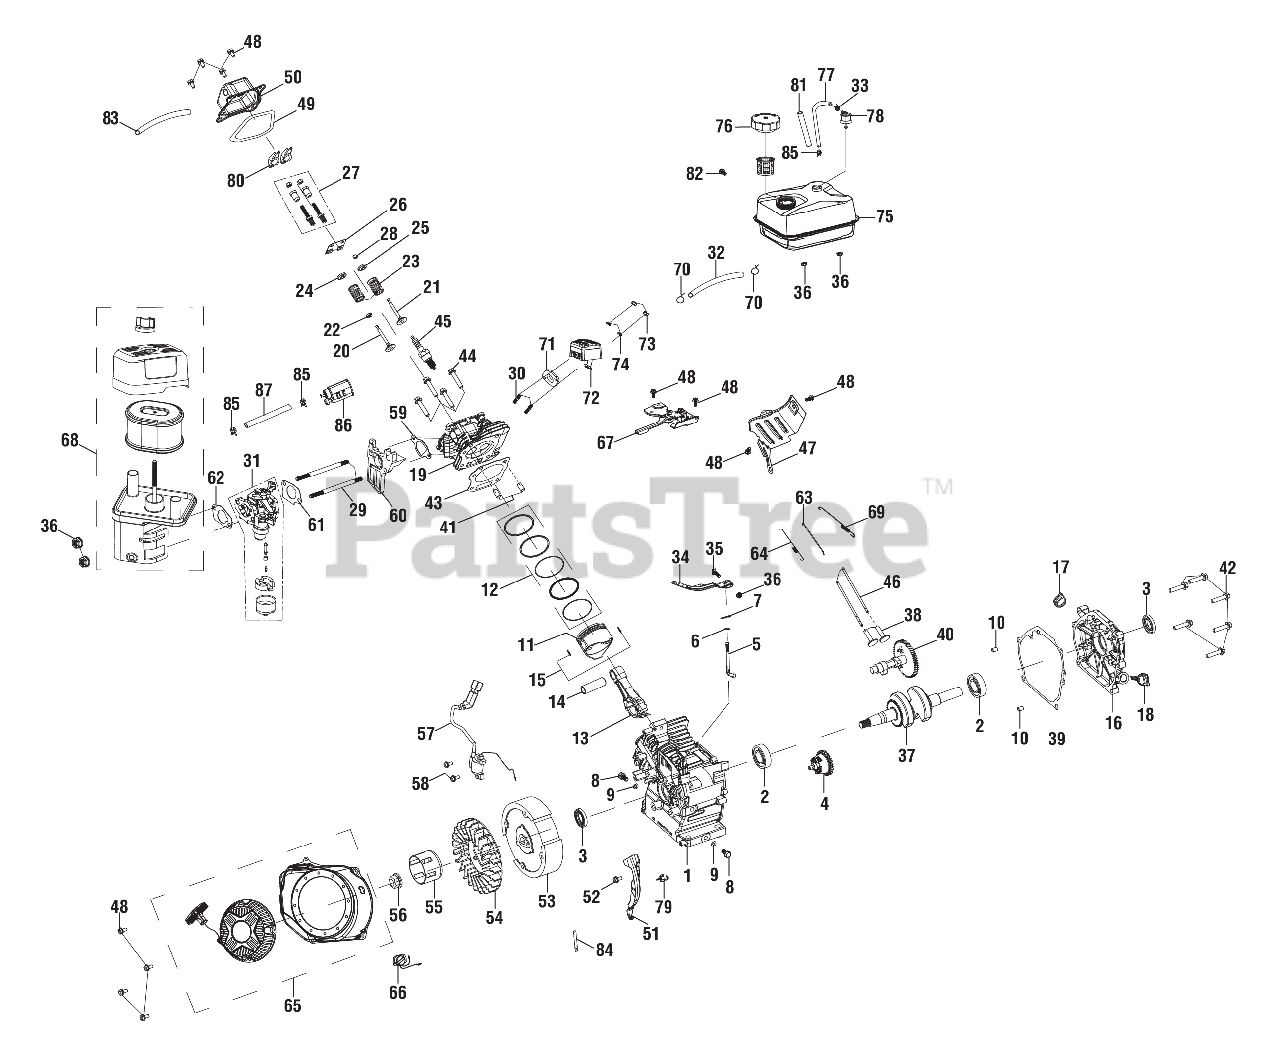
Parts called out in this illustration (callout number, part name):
2	Ball Bearing
4	Governor Assembly
5	Governor Arm Shaft
6	Governor Arm Shaft Washer
8	Drain Plug Bolt
9	Drain Plug Washer
10	Casecover Dowel Pin
12	Scraper Ring Set Piston
13	Connecting Rod Assembly
15	Piston Clip
16	Crankcase Cover Assembly
19	Cylinder Head
20	Intake Valve
21	Exhaust Valve
22	Intake Valve Retainer
23	Valve Spring
24	Intake Valve Spring Seat
25	Exhaust Valve Spring Seat
26	Push Rod Guide Plate
27	Rocker Arm Bolts
31	Carburetor Assembly
33	Fuel Line Clip
34	Governor Arm
35	Governor Arm Bolt
37	Crankshaft Assembly
38	Valve Lifter
39	Casecover Packing
40	Camshaft Assembly
42	Bolt (M8 x 30 mm)
43	Cylinder Head Gasket
44	Bolt (M8 x 60 mm)
48	Bolt (M6 x 12 mm)
49	Headcover Packing
50	Cylinder Head Cover Comp
51	Wind Shiel Comp
52	Bolt (M6 x 20 mm)
53	Flywheel Assembly
54	Recoil Starter Fan
55	Starter Pulley
57	Ignition Coil Assembly
58	Bolt (M6 x 25 mm)
59	Intake Packing
60	Carburetor Insulator
61	Carburetor Packing
62	Empty Filter Gasket
63	Governor Rod
64	Throttle Return Spring
65	Recoil Starter Assembly
66	Switch Assembly
67	Upper Shroud Assembly
68	Air Cleaner Assembly
69	Governor Spring
70	Fuel Line Clip
71	Exhaust Packing
72	Muffler Comp
74	Spring Washer
75	Fuel Tank Assembly
77	Connecting Pipe
78	Manual Choke Assembly
81	Ventilation Tube Protector
82	Bolt (M6 x 28 mm)
83	Breather Tube
84	Wire Harness Clip
85	Fuel Line Clip (95)
86	Carbon Tank Components
87	Connecting Pipe
